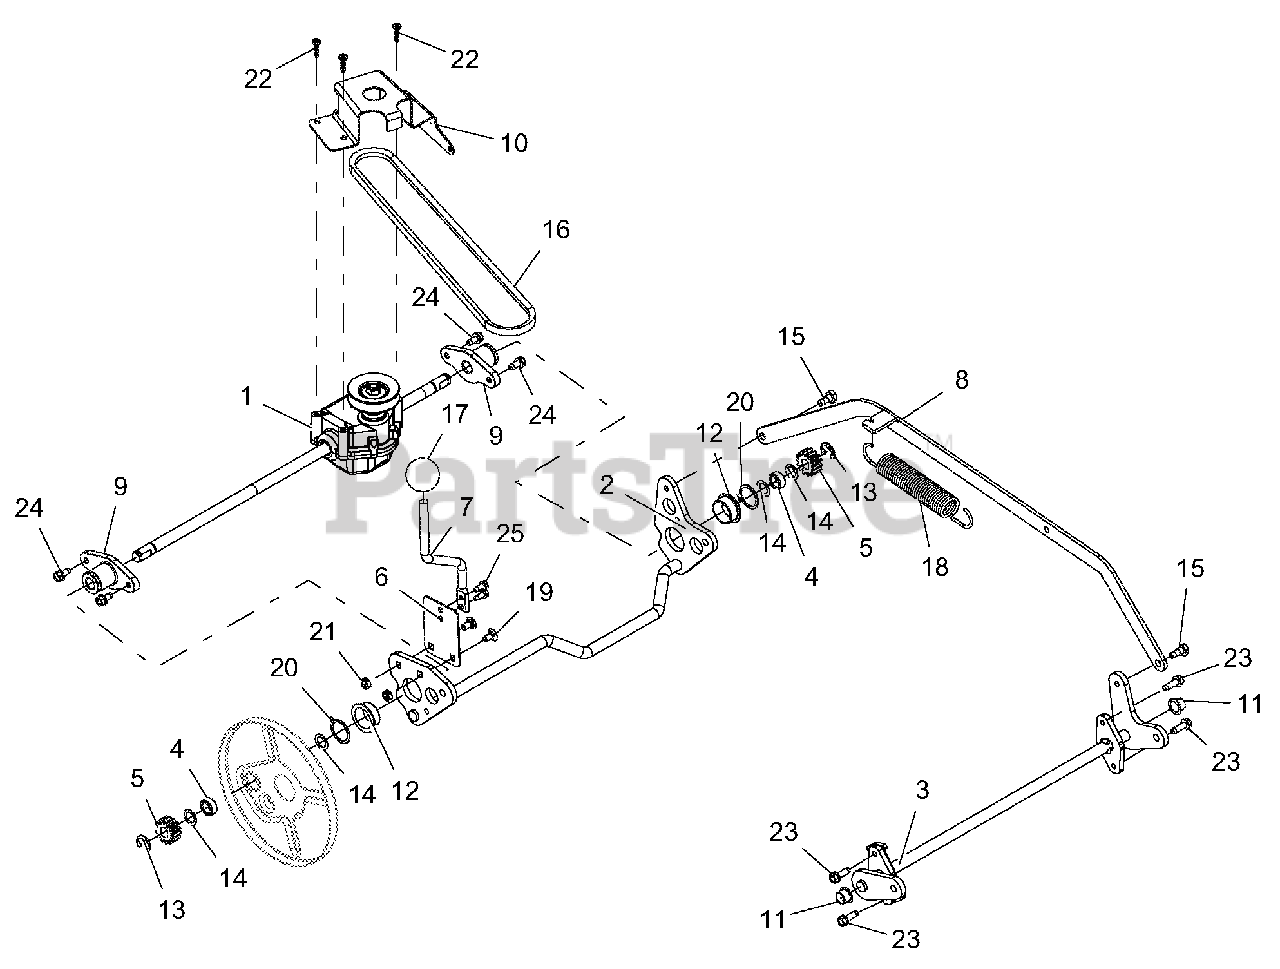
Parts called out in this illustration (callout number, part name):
1	TRANSAXLE, AUTOMATIC, LM, 9:1
2	WMT,RR AXL(SEE BULLETIN B2119)
3	WMT, LM FRONT AXLE
4	BSHG, SPCR.500X.750X.321 PM
5	GEAR, PINION, LM WHEEL DRIVE
6	PLATE, HOC SPRING
7	LEVER, HOC ADJUSTMENT
8	LINK, HOC CONNECT
9	HUB, LM REAR AXLE
10	BRKT, TRANSMISSION BELT GUIDE
11	BUSHING, POLYLINER-.50 SPLIT
12	BSHG-FLG 1.0X1.125X.50X1.375 R
13	RG-RTNG-EXT .500X.042 (E)
14	WASHER, .500X.750X.020 THRUST
15	BOLT, SHLDR .320X.210X.25-20
16	V-BELT, 3L-WRAPPED
17	KNOB,BALL -BLACK 1.47" .375-16
18	SG-TENS .121X1.00X6.5 WLD 12
19	@BLT-RDHDSQNK .25-20X.50 G5YZ
20	RG-RTNG-EXT 1.00X.042
21	NUT-LK-CTR JAM .25-20 YWZC
22	SCR-TAP 10-14X.75PLSTITE BLKOX
23	SCR-TAP-PM .25-20X.75 TR YWZ
24	SCR-TAP .25-20X.50 HWH TR YWZ
25	@SCR-TAP 12-24X.50 HWH TR YWZC
